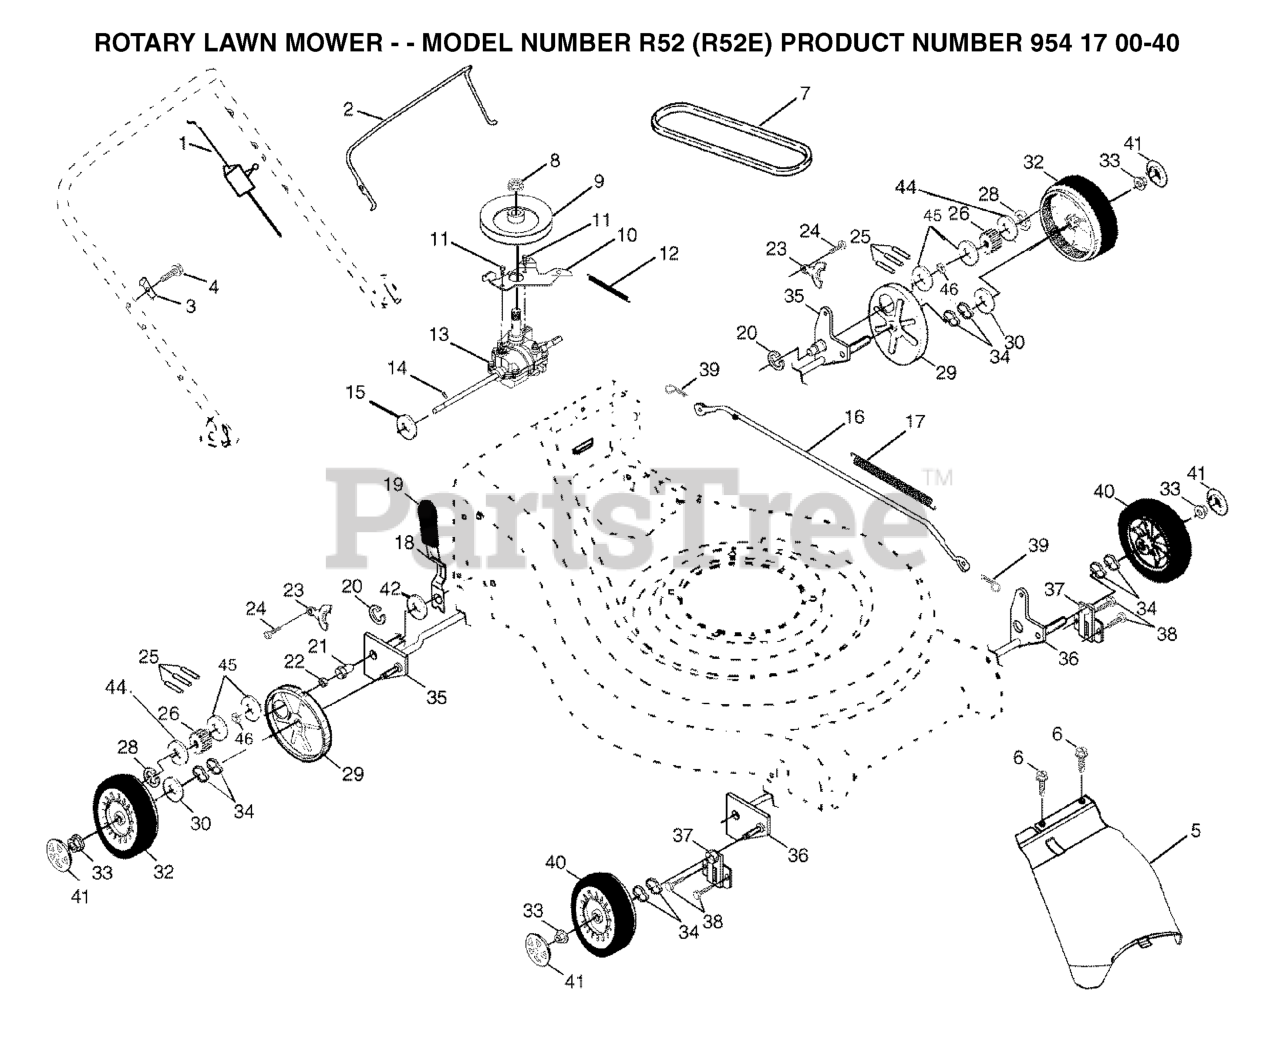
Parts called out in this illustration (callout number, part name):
1	CABLE.DRIVE.21.RWGD.
2	BAIL.CONT.DR.21.RWGD.BLACK
3	DOWNSTOP BRACKET
5	DRIVE COVER
8	FLANGED LOCKNUT 3/8-16 ZINC
10	BELT GUIDE
11	Screw, Hex Washer Head #10-24 x .668
13	TRANSMISSION ASM. (WALK)
14	PIN.SPRING.THRUST
15	THRUST WASHER
16	ROD CONNECTING
17	SPRING
18	SPRING
19	KNOB
21	RP BEARING SUPPORT
22	BEARING, BALL
23	BRACKET
25	PAWL.DRIVE.ETCHED
26	PINION.DRIVE.WALK
28	E-RING 7/16 RE
29	DUST COVER, WHEEL
30	WASHER FLUT
32	WHEEL.9X2.PR.LP.RADIAL.BK.BB.3
33	HEX FLANGE LOCKNT
34	WAVE WASHER
35	SHAFT ASSY
36	SHAFT ASSY
37	RETAINER.FRONT.SHAFT
39	RETAINER CLIP
40	WHEEL ASMBLY FRONT
41	CAP.HUB.ARC.SPOKE.8".LP
42	WASHER.ZINC.PLATED
45	WASHER.BELLEVILLE (3 2 LB)
